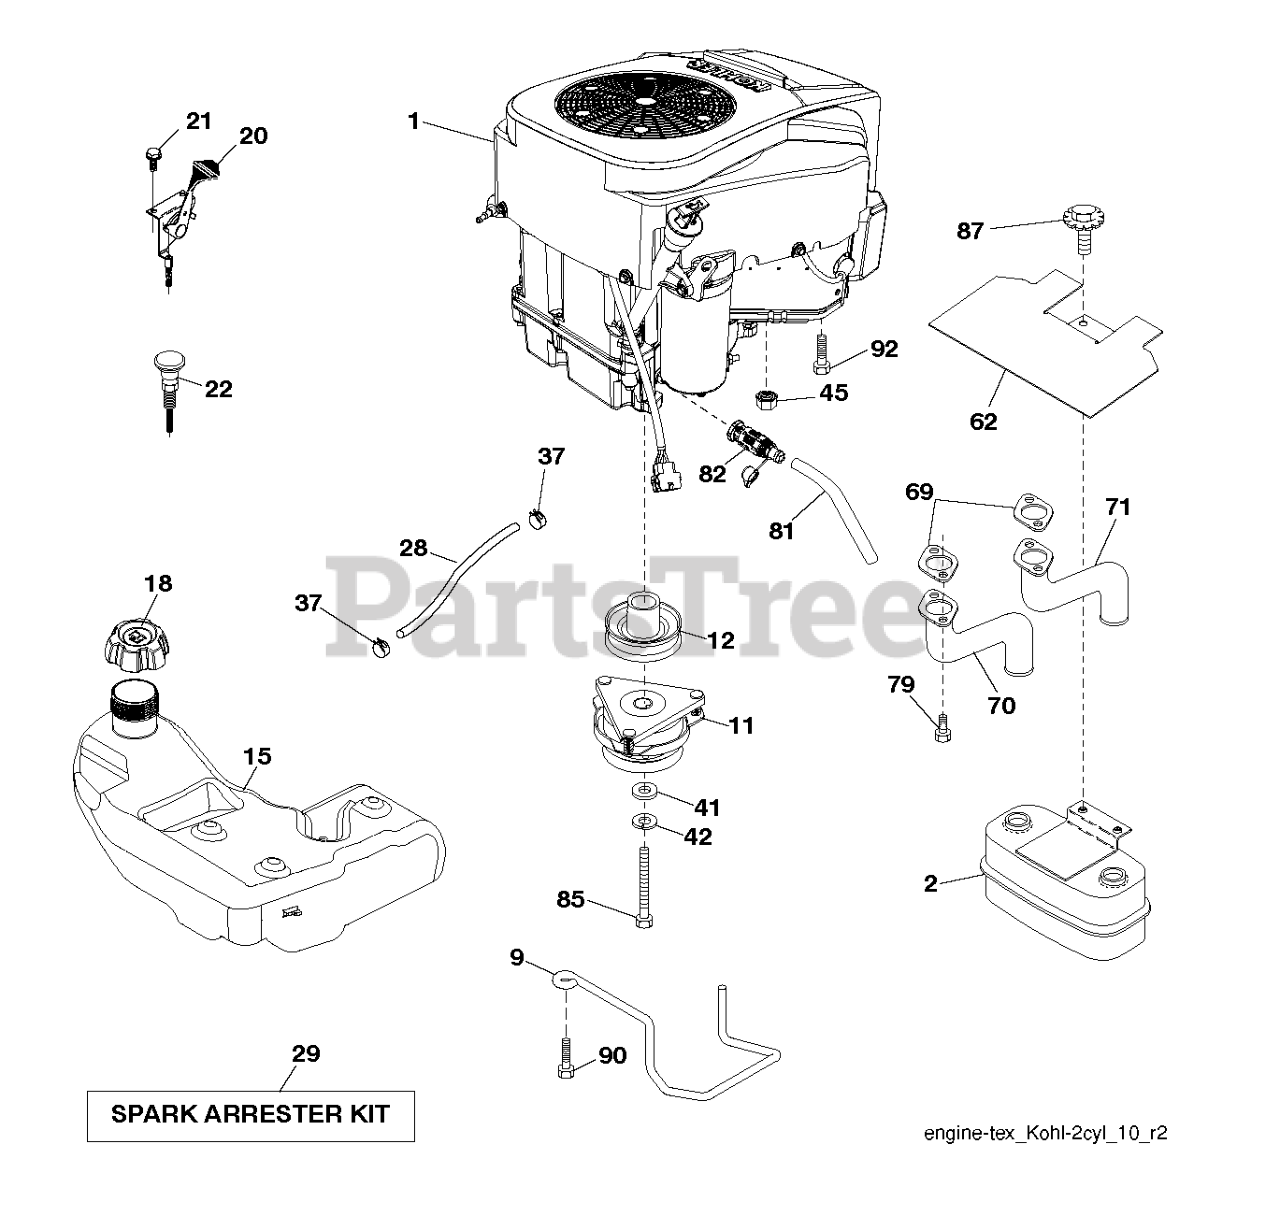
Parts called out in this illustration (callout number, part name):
2	MUFFLER.ASM.TWN.EXTNDED.DFLCTR
9	KEEPER.BELT.ENGINE.4.2
11	CLUTCH.ELECTRIC.LT.48"*
12	PULLEY.ENGINE.TUFFTORQ
15	RP_TANK.ASSY.3.GAL.EPA
18	CAP.ASM.FL.RITCH.3"E10.SYM.498
20	THROTTLE CONTROL
21	SCREW.#10 X 0.750.BOS
22	CONTROL.CHOKE.ERGO.PUSH-IN.BLA
28	LINE.FUEL.64"REAR.EMIS
29	KIT.SPARK ARRESTOR 794945 B&S
37	HOSE CLAMP
42	LOCKWASHER
45	NUT
62	SHIELD.HEAT.MUFFLER
69	GASKET.EXHAUST.KOHL.CV18-CV26
70	RP.PIPE-EXHAUST LH
71	RP.PIPE-EXHAUST RH
79	SCREW.SOCKET HD.5/16-1
81	TUBE, DRAIN OIL ASM.
82	VALUE.OIL.DRAIN
85	BOLT HEX 7/16-20X4-1/4"
87	BOLT.5/16-18UNCX3/4 W/SEMS.BLK
90	SCREW 3/8-16X1
92	SCREW 3/8-16X1
